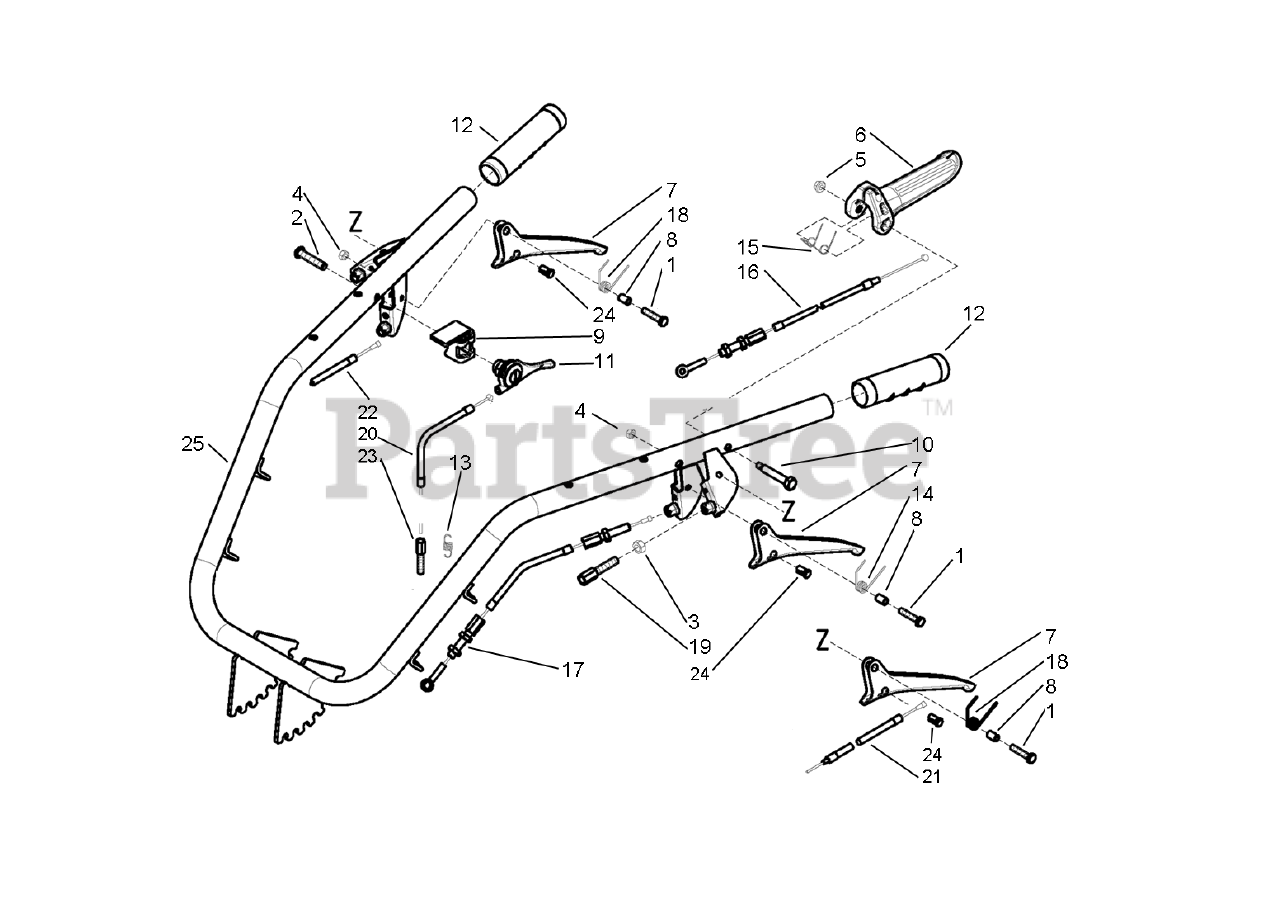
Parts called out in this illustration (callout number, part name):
1	SCREW TE M6X25
2	SCREW
3	NUT M8
4	SELFLOCK NUT M6
5	SELFLOCK NUT M6
6	LEVER
7	LEVER
8	SPACER
9	PANEL
10	LEVER PIN
11	LEVER, THROTTLE
13	SPRING
14	SPRING
15	SPRING
16	CABLE & SHEATH, OPC
17	CABLE & SHEATH, CLUTCH
18	SPRING
19	ADJUSTING SCREW
20	CABLE & SHEATH, THROTTLE
21	CABLE & SHEATH, BRAKE
22	CABLE & SHEATH, HANDLEBAR REL
23	ADJUSTING SCREW
24	CABLE CLAMP
25	HANDLEBAR
